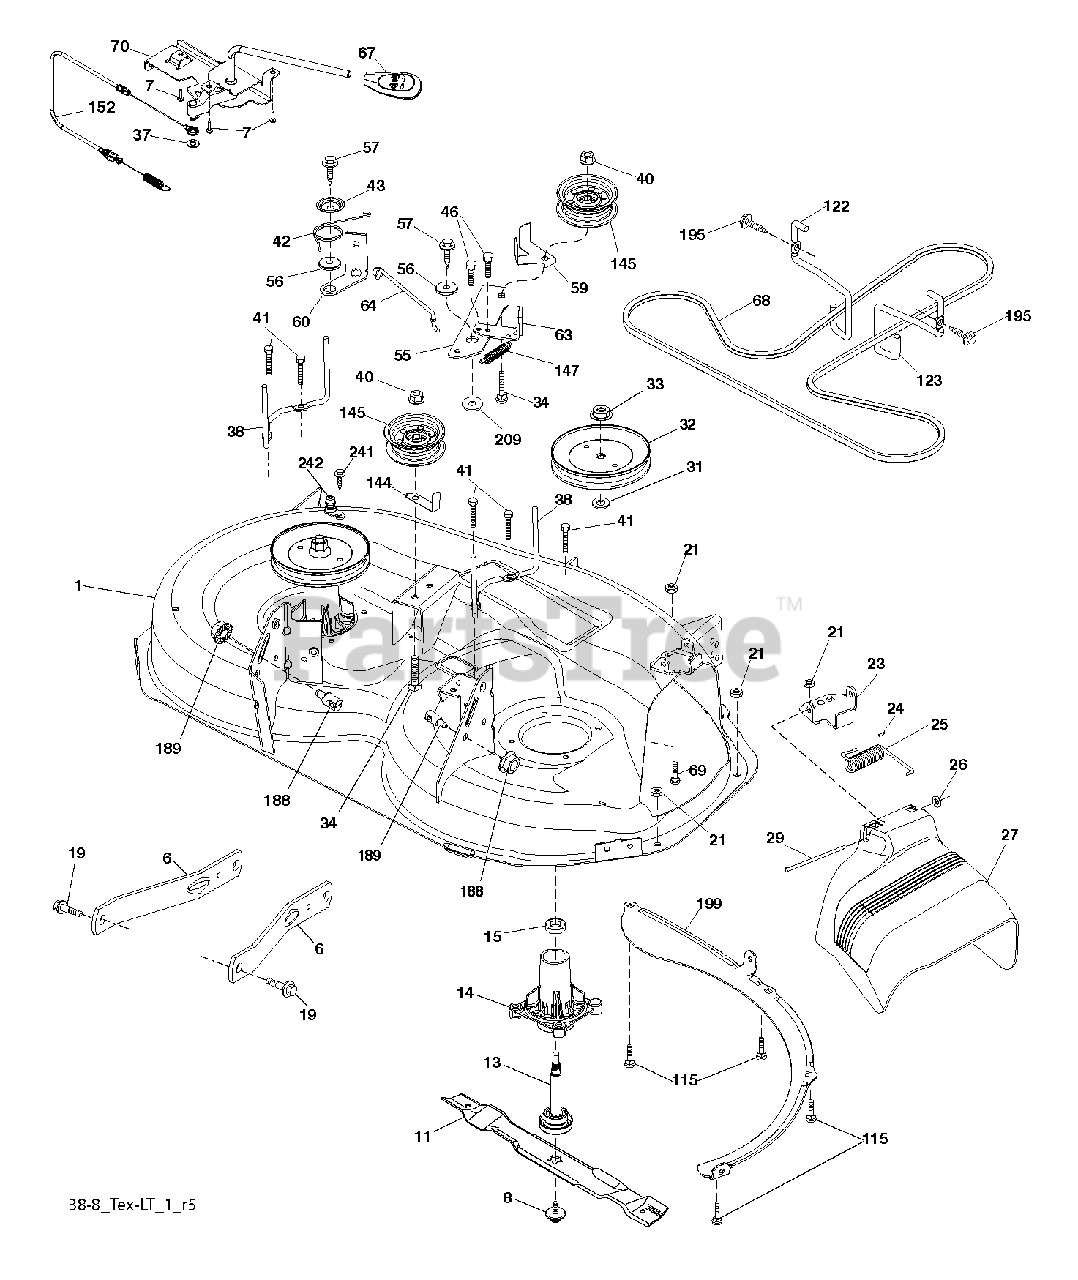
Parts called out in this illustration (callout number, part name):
1	DECK.WELDMENT.38"TEX.N/GWB.BLU
6	ARM.SUSPENSION.MOWER.R
7	SCREW.#10 X 0.750.BOS (2 2)
8	BOLT.WASHER.ASM.7/16-2
11	BLADE 38" PREMIUM
13	SHAFT.ASM.MDRL.N/GREASE.38
14	HOUSING.MANDREL.4PT.
15	BEARING
19	BOLT.SHOULDER
21	LOCKNUT
23	BRKT.DEFLECTOR.38"2005+
24	CAP-SLEEVE LT
25	SPRING.TORSION.DEFLECT
26	NUT PUSH M
29	ROD.HINGE
31	WASHER.SPACER.MANDREL
32	PULLEY.MANDREL.5.0.PD.38"
33	NUT.FLANGE.LOCK.TOP
34	BOLT.3/8-16X1.50
37	WASHER
38	KEEPER BELT LH MANDREL
40	NUT LOCK FLG 3/8-16 UNC
41	BOLT.HEX.WASHR.HED.313-18X1.19
42	SPRING.TORSION.BRAKE
43	SRPING.TORSION.RETAINE
46	SCREW.1/4-20X5/8
55	IDLER.ARM
56	SPACER.RETAINER
57	SCREW 3/8-16X1
59	GUARD, BELT
60	ARM BRAKE MOWER RH 38"
63	ARM BRAKE MOWER RH
64	LINK BRAKE
67	HANDLE.CLUTCH.CABLE.LT
69	BOLT
70	CLUTCH.ASM.MANUAL.LT.PRED
115	BOLT
122	KEEPER BELT ENGINE LH
123	KEEPER BELT RH
144	KEEPER BELT
145	PULLEY.IDLER.48"PRIMARY
147	SPRING RETURN
152	CABLE.CLUTCH.MANUAL.
188	STUD.FASTNER.W/ANTI-ROTATE
189	NUT LOCK HEX FLANGE 5/16-18
195	SCREW, 3/8-16X3/4
199	BAFFLE.VORTEX.FRONT.38"
209	WASHER 12/32X2X10GA
241	SCREW.TT.#10-32X.5.3/8.FLANGE
242	PORT.WASHOUT
